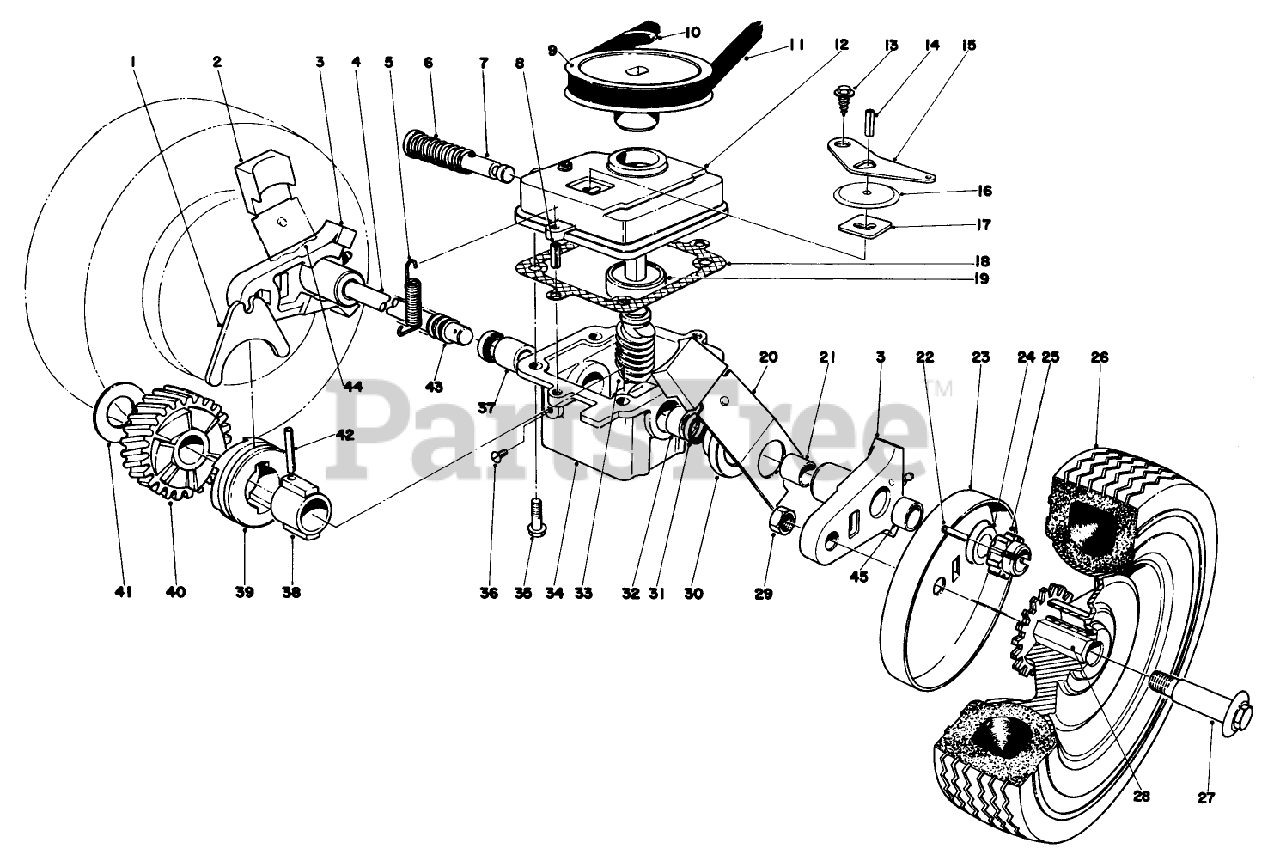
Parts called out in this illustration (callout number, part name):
1	SHIFTER FORK
2	KNOB-ARM
3	PIVOT ARM ASM
4	DRIVE SHAFT (SERVCE)
5	Spring-Tension
6	SPRING
8	3/16 X 1/2 ROLL PIN
10	PUSH-ON 93-3236
11	BELT-V
14	PIN-ROLL
15	SHIFTER ARM
16	TRANS DUST COVER
17	LATCH PLATE
18	GASKET
21	BUSHING
23	WHEEL COVER
24	WASHER-THRUST
30	End Cap
32	Bushing
33	WORM SHAFT & GEAR SET
34	GEAR CASE ASM
36	NYLON SCREW
38	SLEEVE
39	CLUTCH JAW
40	Helical Gear
41	THRUST WASHER
43	COVER-SHAFT, DRIVE
44	SPRING ARM ASM SP RH
45	BUSHING
